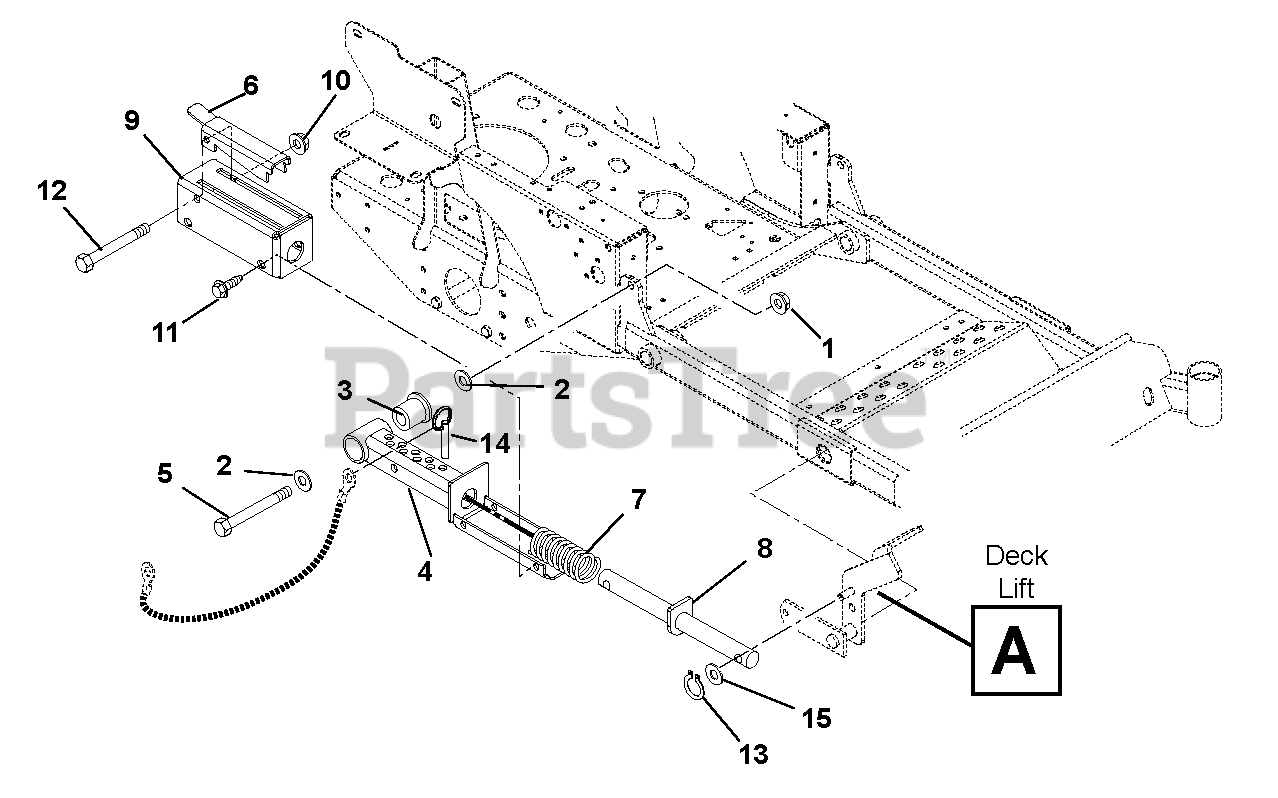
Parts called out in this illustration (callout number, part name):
1	Nut, Locking Top Flange .50-13
2	Washer, Flat Steel .531 x 1.25 x .10
3	Bearing, Pedestal
4	Weldment, Mechanical Lift
5	Bolt, Hex .50-13 x 3.75 Grade 5
6	Lock-Up, Mechanical Lift
7	Spring, Compression 1.13 x 1.48 x 5.10
8	Weldment, Mechanical Lift Shaft
9	Weldment, Mechanical Lift Cover
10	Nut, Nyloc Flange 3/8-16
11	Screw, Tapping .38-16 x .50 Hex Washer Head
12	Bolt, Hex .38-16 x 3.25 Grade 5
13	Ring, Retaining External .50 x .05
14	Pin, Spring Ball .375 O.D. x 1.50
15	Washer, Flat Steel .531 x 1.25 x .10
